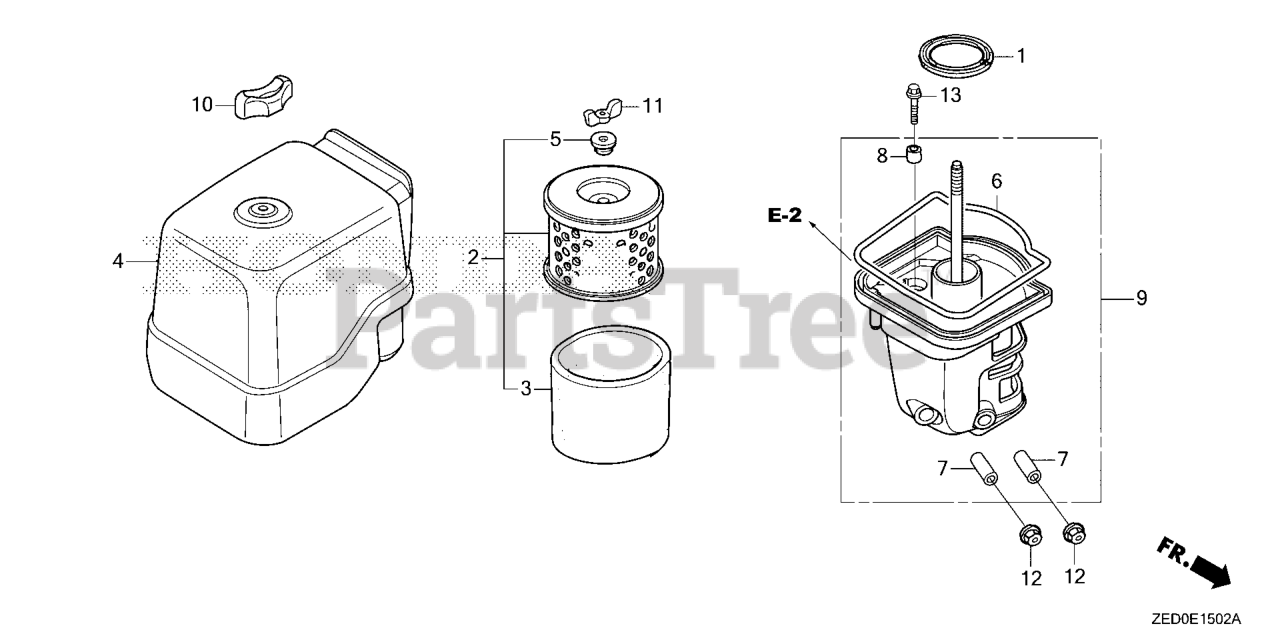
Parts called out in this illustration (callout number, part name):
1	GASKET, ELBOW
2	ELEMENT, AIR CLEANER
3	FILTER (OUTER)
4	COVER ASSY., AIR CLEANER
5	GROMMET, AIR CLEANER
6	SEAL, AIR CLEANER COVER
7	COLLAR, AIR CLEANER Use from Engine SN 1786085.
8	COLLAR B, AIR CLEANER
9	ELBOW, AIR CLEANER
10	NUT, AIR CLEANER
11	WINGNUT, TOOL BOX SETTING
12	NUT, FLANGE (6MM)
13	BOLT, FLANGE (6X20)
